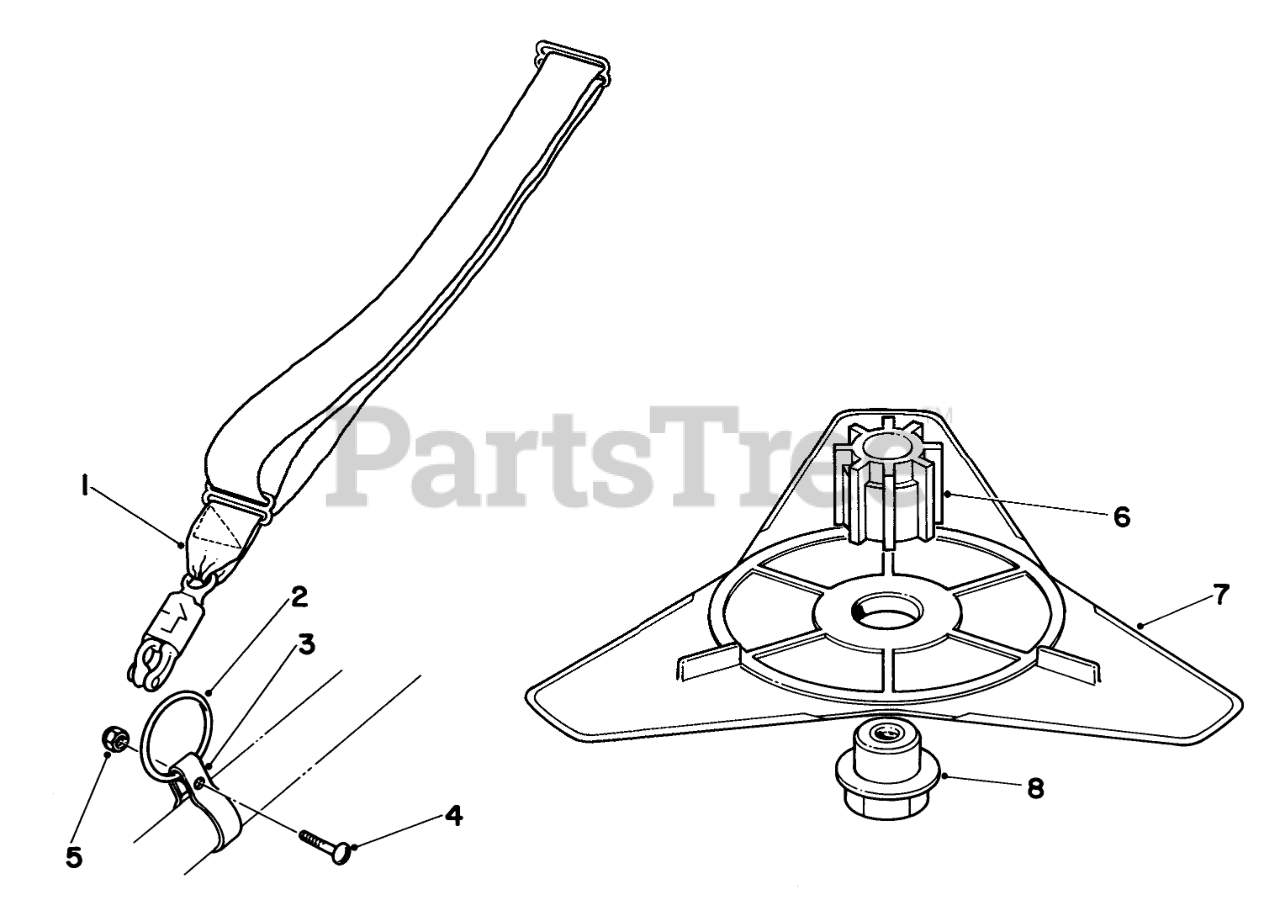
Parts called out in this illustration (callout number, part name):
1	Shoulder Strap
2	Ring
3	Clamp
4	10-24 X 5/8 PAN HD MS
5	NUT-LOCK, NI
6	BLADE ADAPTER
7	FLEX BLADE PKG
8	ADAPTER NUT
